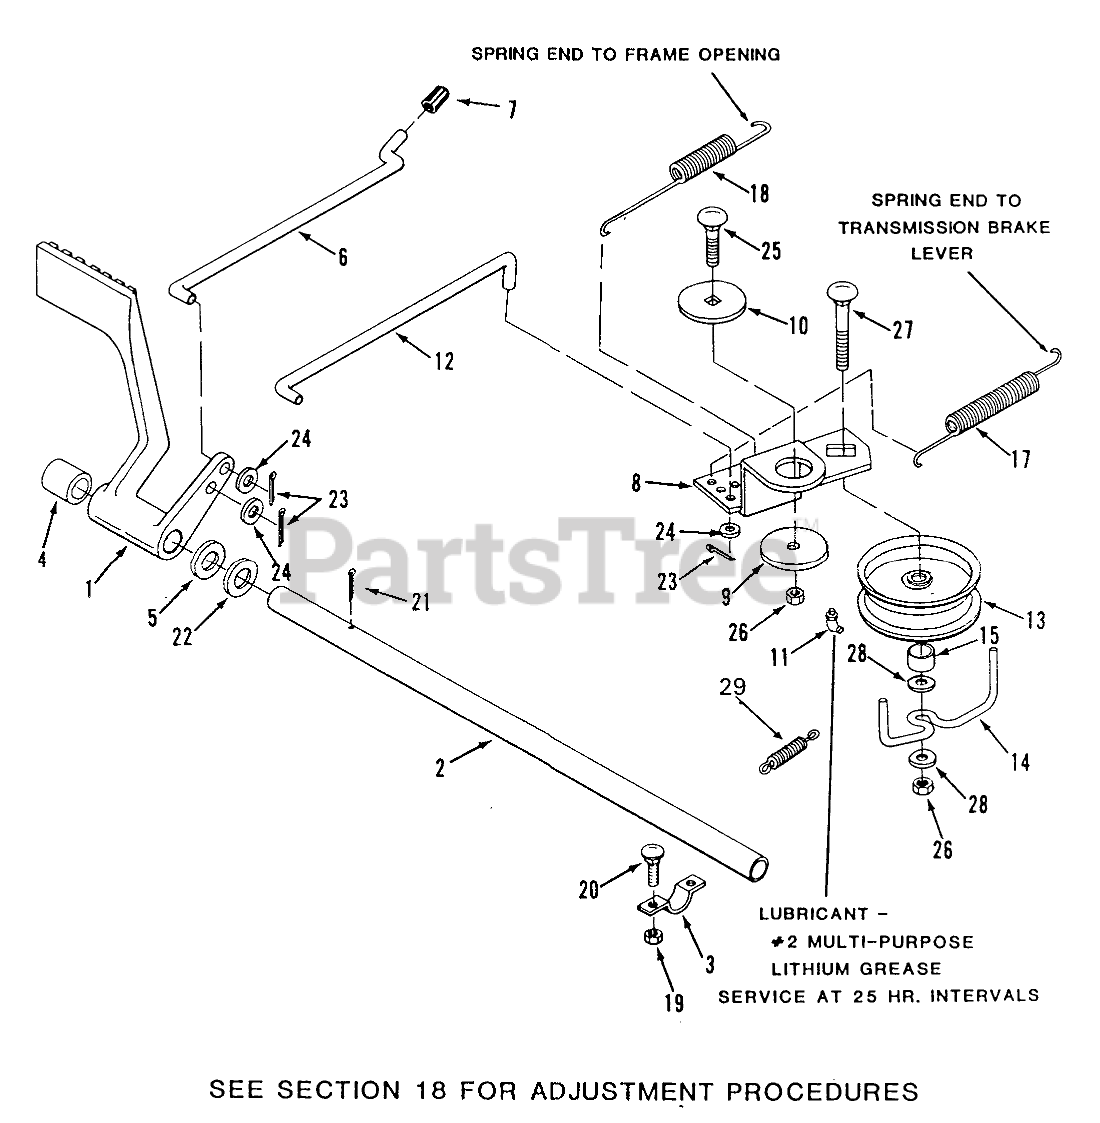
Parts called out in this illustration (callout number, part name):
1	PEDAL BRAKE R
2	SHAFT PEDAL
3	CLAMP
4	SPACER
5	WASHER-WAVE
6	Lock Rod
8	ARM-IDLER R
9	BUSHING
10	WASHER-BEARING
11	Fitting-Grease
12	ROD-CLUTCH/BRAKE B
13	PULLEY IDLER
14	GUIDE-BELT
15	SPACER
17	SPRING - BRAKE
18	SPRING - CLUTCH
19	Nut
20	Bolt
22	Washer
23	Cotter Pin
24	WASHER 5/16 SAE
25	Bolt
26	NUT
27	Bolt
28	Washer
29	EXTENSION-SPRING
